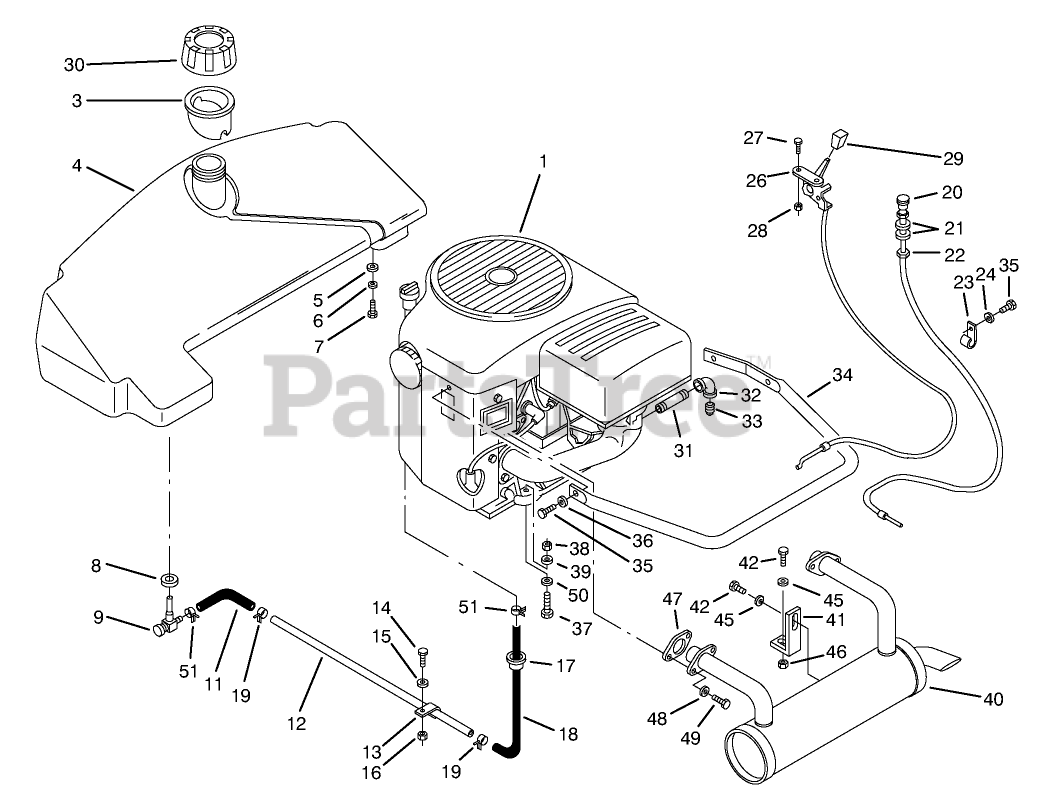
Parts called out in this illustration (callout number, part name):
3	FUNNEL-FUEL TANK
4	TANK-FUEL ASS'Y
5	WASHER-FLAT
6	WASHER-LOCK
7	SCREW-HH
9	VALVE-FUEL
12	TUBE FUEL LINE
13	J-CLIP
14	SCREW-HH
15	WASHER-PLAIN
16	NUT-LOCK, NI
17	BUSHING-NYLON 1.093
18	Hose-18" Fuel
19	CLAMP-FUEL LINE
20	CONTROL-CHOKE
21	WASHER-FLAT
22	NUT-HEX PALNUT
23	CLIP
24	WASHER-FLAT
26	CONTROL-THROTTLE
27	SCREW-PPH
28	NUT-LOCK, NI
30	GAS CAP ASM
31	NIPPLE-3/8 X 2.5
32	ELBOW 3/8 90 DEG
34	GUARD-AIR CLEANER
35	SCREW-HH
36	WASHER-LOCK
37	SCREW-HH
38	NUT-LOCK, NI
39	WASHER-PLAIN
40	EXHAUST-MUFFLER
41	BRACKET-MUFFLER
42	SCREW-HH
45	WASHER-PLAIN
46	NUT-LOCK, NI
47	GASKET
48	WASHER-LOCK
49	SCREW-HSH
50	WASHER
51	CLAMP-HOSE
